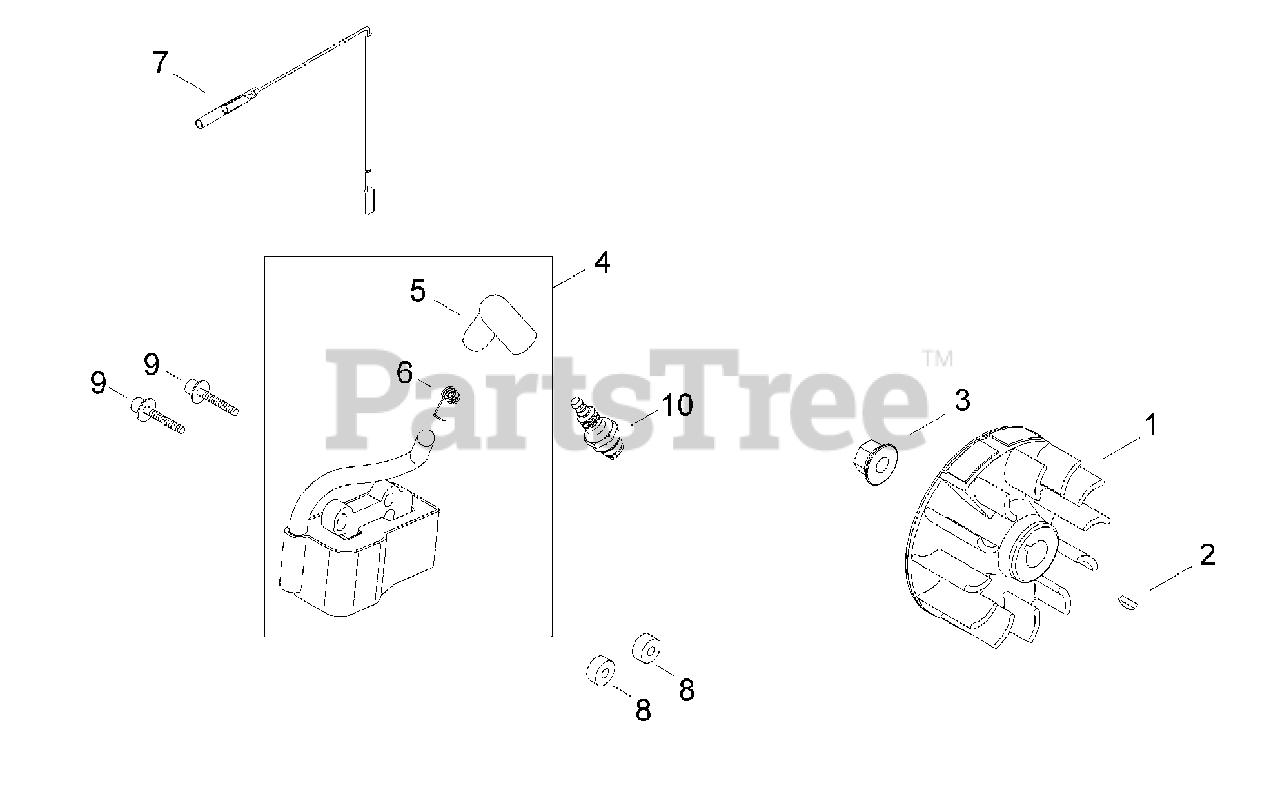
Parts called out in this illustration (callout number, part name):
1	FLYWHEEL
2	KEY, WOODRUFF 3×10
3	NUT M8
4	COIL ASSY, IGNITION
5	CAP, SPARK PLUG
6	TERMINAL, SPARK PLUG
7	LEAD - IGNITION L= 220 MM
8	INSULATOR 4.2×11×6
9	BOLT M4×26
10	SPARK PLUG - CMR5H
